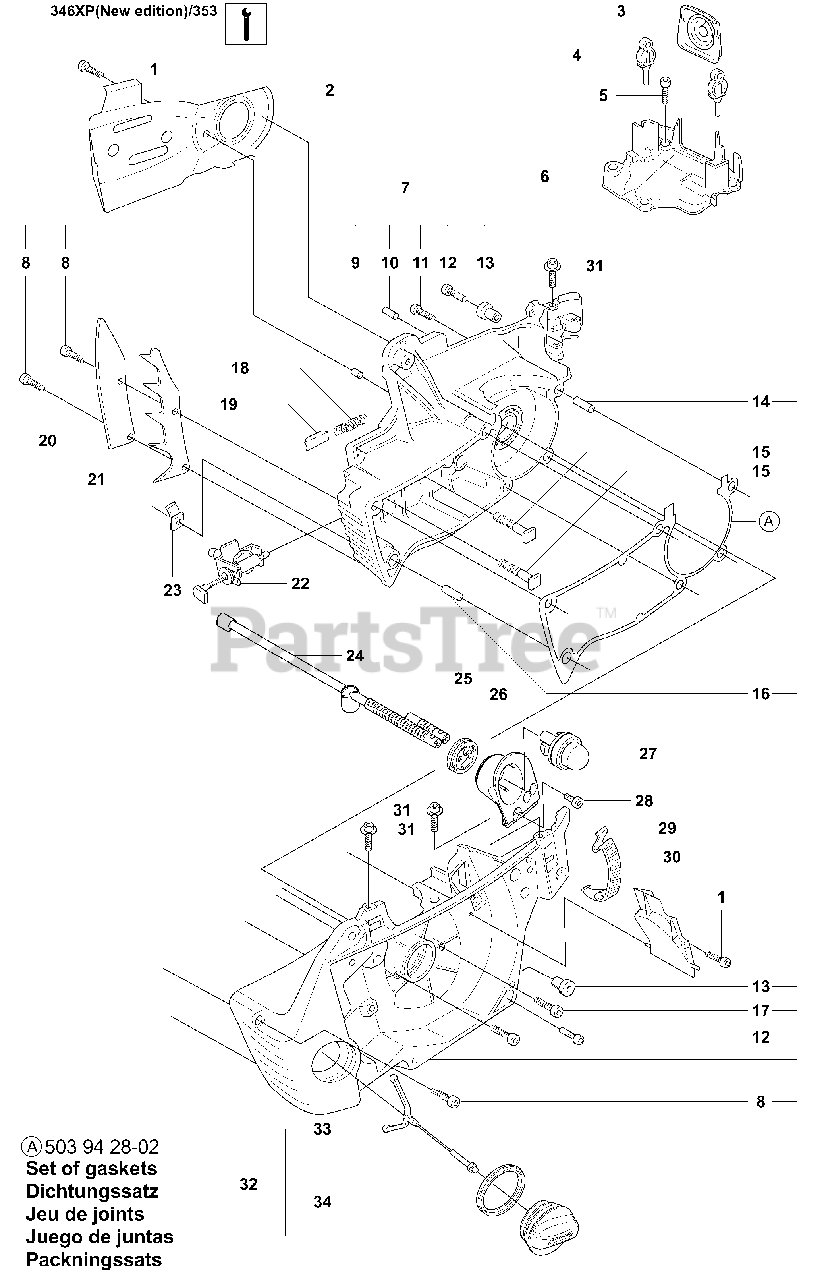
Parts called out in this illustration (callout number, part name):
2	CHAIN GUIDE PLATE
6	CARBURETOR AREA BASE
7	CRANKCASE ASSY
13	MOVEMENT LIMITER
18	LOCK SPRING
21	FELLING DOG
22	CHAIN TENSIONER
23	CHAIN CATCHER
24	RP HOSE
26	BRACKET
27	AIR PURGE BUBBLE
28	SCREW IHSCT
29	BUCKLE ORANGE
29	CLIP GRAY
32	OIL TANK CAP GREY
34	OILCAP GASKET
A	GASKET SET
